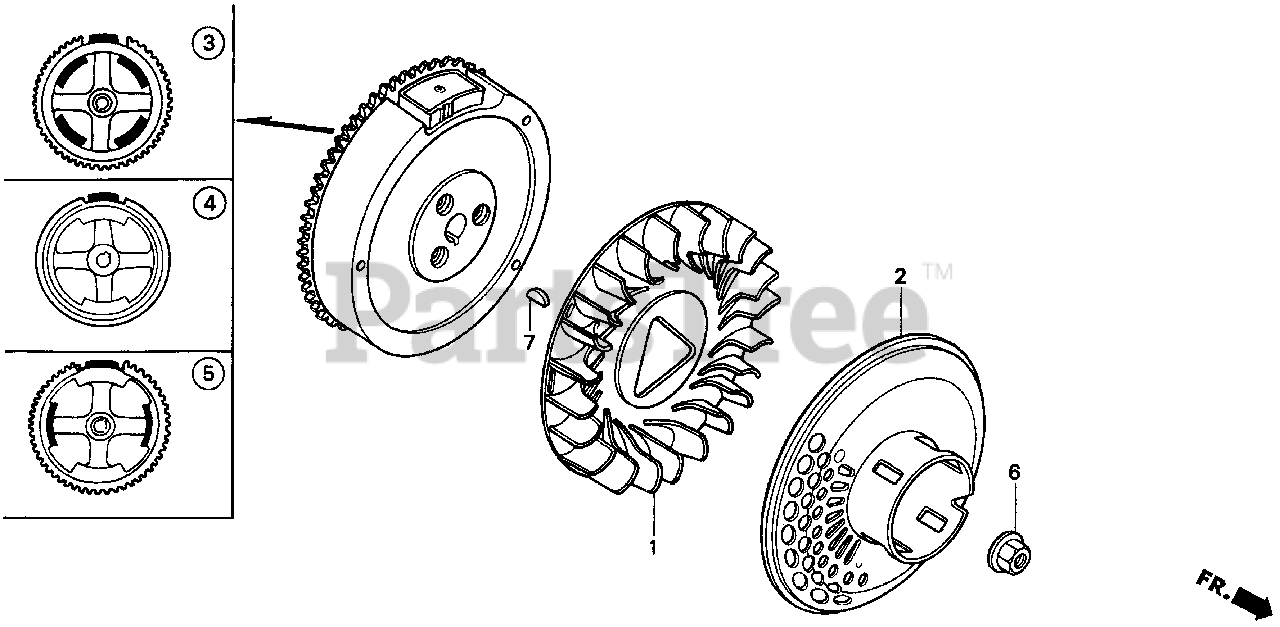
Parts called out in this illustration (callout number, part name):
1	FAN, COOLING
2	PULLEY, STARTER (SCREEN GRID)
5	FLYWHEEL (SEL-LAMP)
6	NUT, SPECIAL (16MM) (1)
6	NUT, SPECIAL (16MM)
7	KEY, SPECIAL WOODRUFF (25X18)
